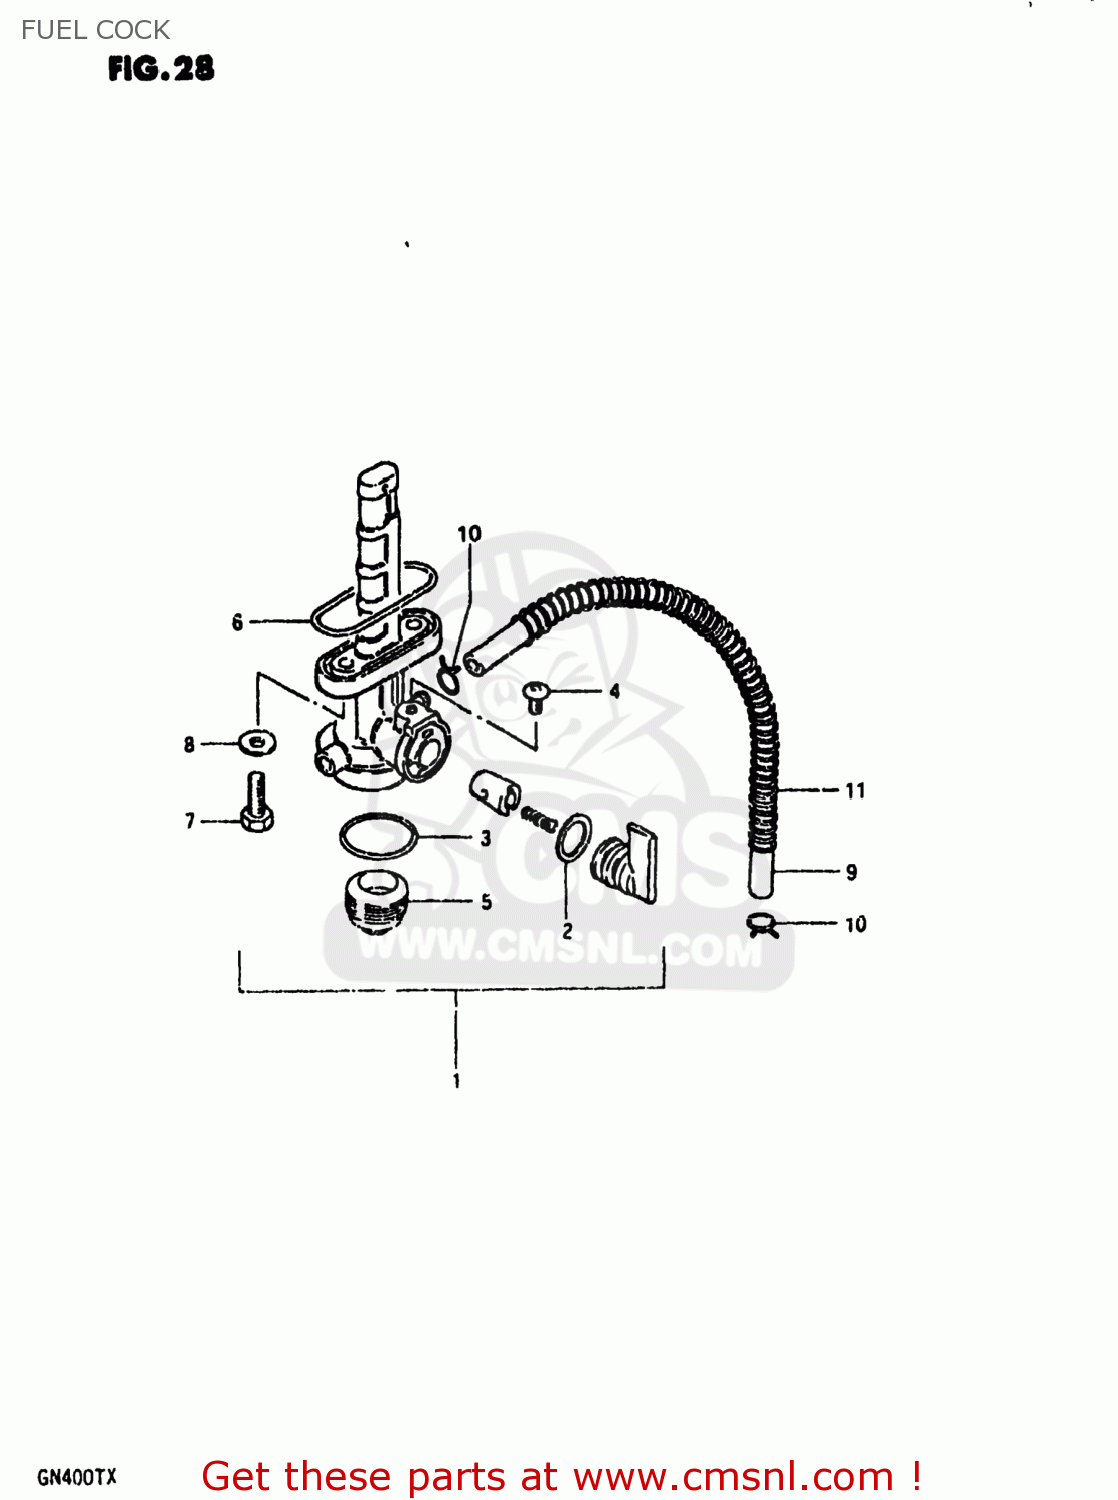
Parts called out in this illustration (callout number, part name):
1	COCK ASSEMBLY,FUEL
2	O-RING
3	GASKET,FILTER (NAS)
4	SCREW,FUEL COCK LEVER
5	CUP,STRAINER
6	O RING,FUEL COCK
7	BOLT(6X20)
8	GASKET
9	HOSE
10	CLIP
11	SPRING
